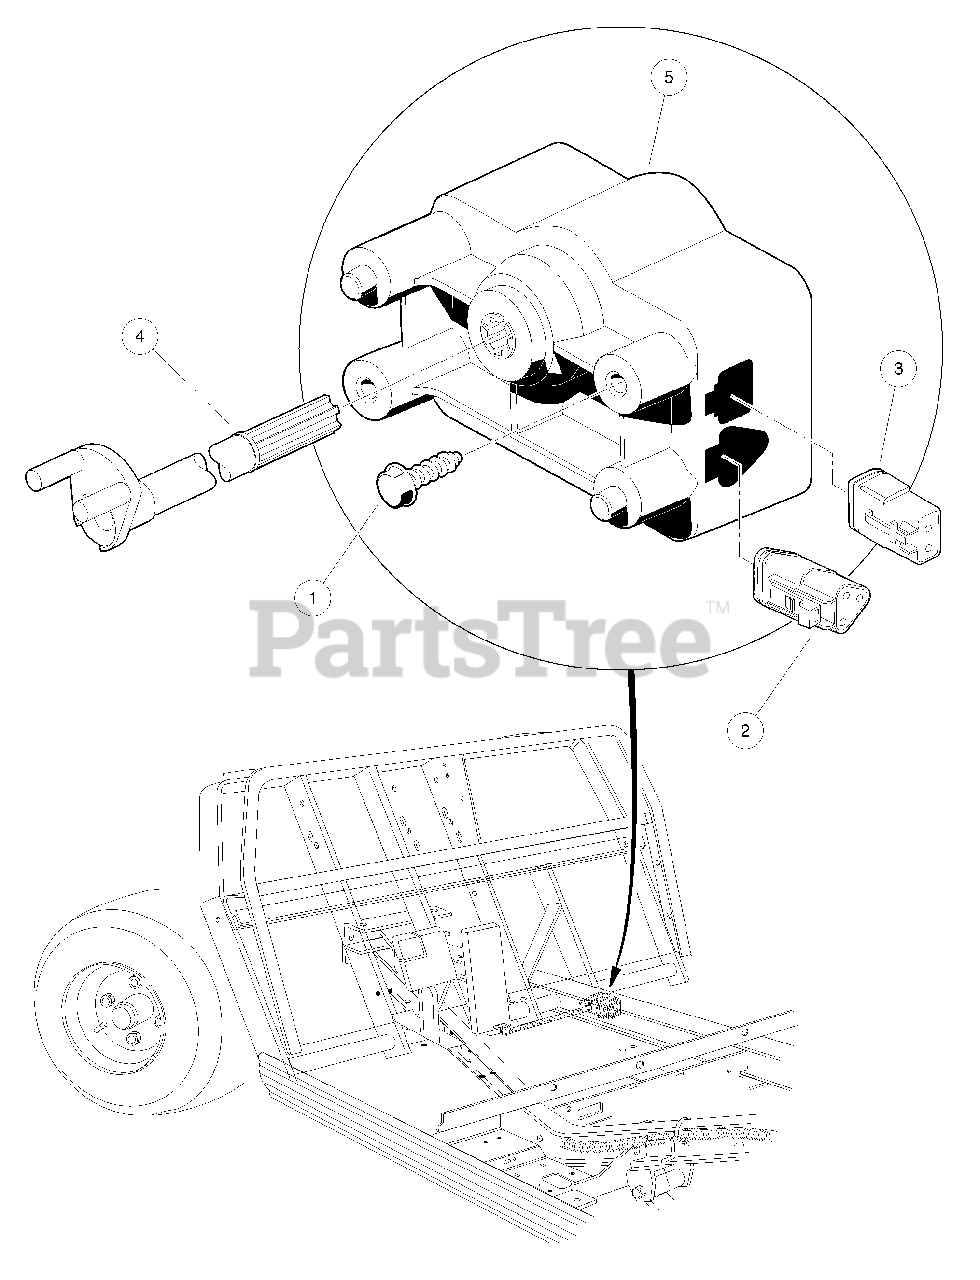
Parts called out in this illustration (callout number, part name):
1	Screw, #12-16 X 0.625 Hi-Lo
2	Kit, 3-Pin Wedge Lock
3	Kit, 2-Pin Wedge Lock
4	Bar, Drive, Cast
